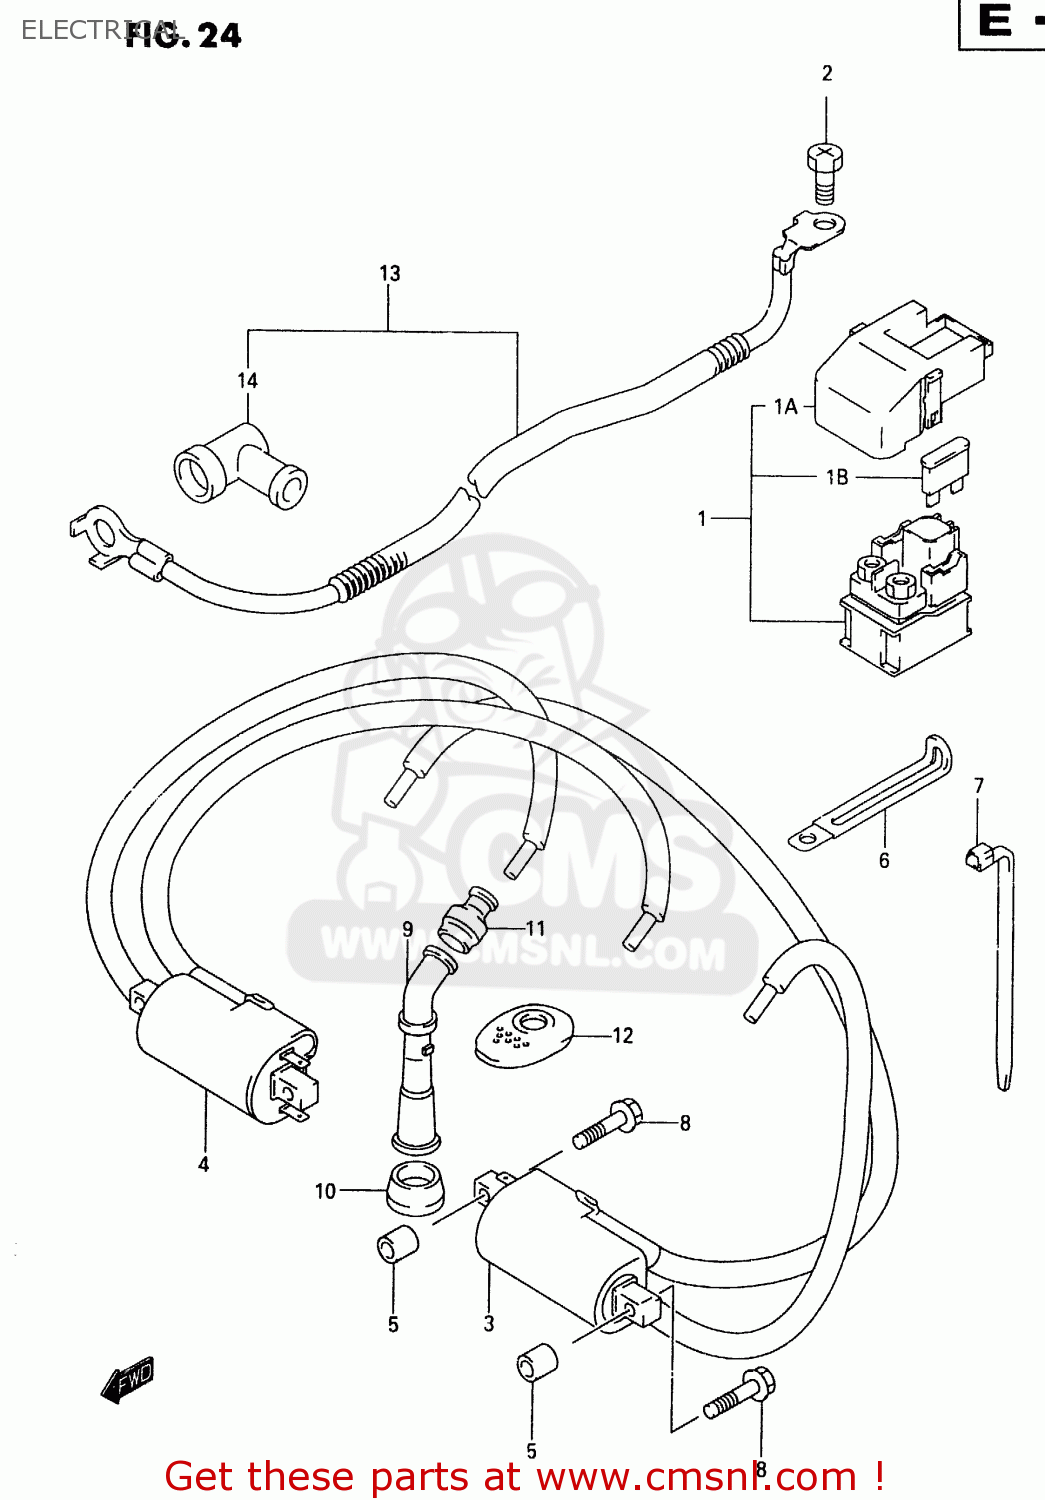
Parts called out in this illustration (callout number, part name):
1	RELAY ASSY,STARTING MOTOR
1A	COVER,RELAY ASSEMBLY
1B	FUSE(30A)
2	SCREW(6X8)
3	COIL ASSY,IGNITION
4	COIL ASSY,IGNITION
5	SPACER(6.2X12X14)
6	CLAMP(L:65)
7	CLAMP(L:235)
8	BOLT (6X45)
9	CAP,SPARK PLUG
10	SEAL,SPARK PLUG CAP
11	SEAL,HIGH TENSION CORD
12	COVER,SPARK PLUG CAP
13	WIRE,BATTERY MINUS
14	CAP,STARTER MOTOR TERMINAL
